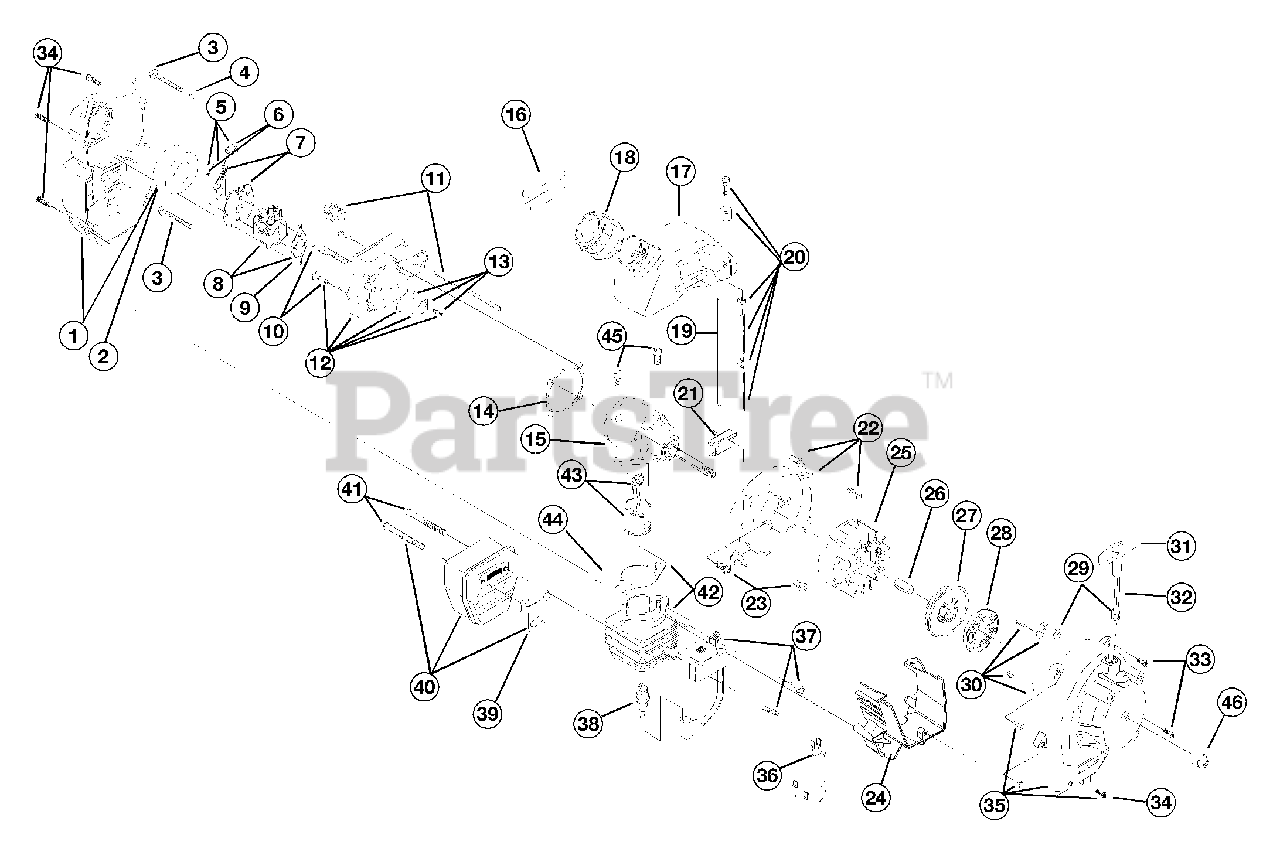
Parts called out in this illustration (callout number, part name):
1	Air Cleaner/Muffler Cover Assembly
2	Air Cleaner Filter
3	Carburetor Mounting Screw Assembly
4	Wavey Washer
5	Choke Lever Assembly
6	Choke Knob and Screw
7	Choke Lever and Plate
8	Carburetor Assembly
9	Carburetor Gasket
10	Carb Mount Screw
11	Primer and Hose Assembly
12	Carb Mount Assembly
13	Reed Assembly
14	Carburetor Mount Gasket
15	Crank Case Service Assembly
16	Rear Mounting Pad
17	Fuel Tank Assembly
18	Fuel Cap Assembly
19	Fuel Return Line
20	Fuel Line Assembly
21	Front Mounting Pad
22	Shroud Assembly
23	Shroud Screw
24	Shroud Extension
25	Flywheel Assembly
27	Recoil Pulley Assembly
28	Recoil Spring
29	Rope Guide
30	Pulley Retainer Assembly
31	Pull Handle
33	Housing Screw
34	Cover Screw
35	Starter Housing Assembly
36	Wire Lead Assembly
37	Module Assembly
38	Spark Plug
39	Exhaust Gasket
40	Muffler Assembly
41	Muffler Mounting Bolt Assembly
42	Cylinder Assembly
43	Piston and Rod Assembly
44	Cylinder Gasket
45	Cylinder Bolt
46	Crankshaft Extension
